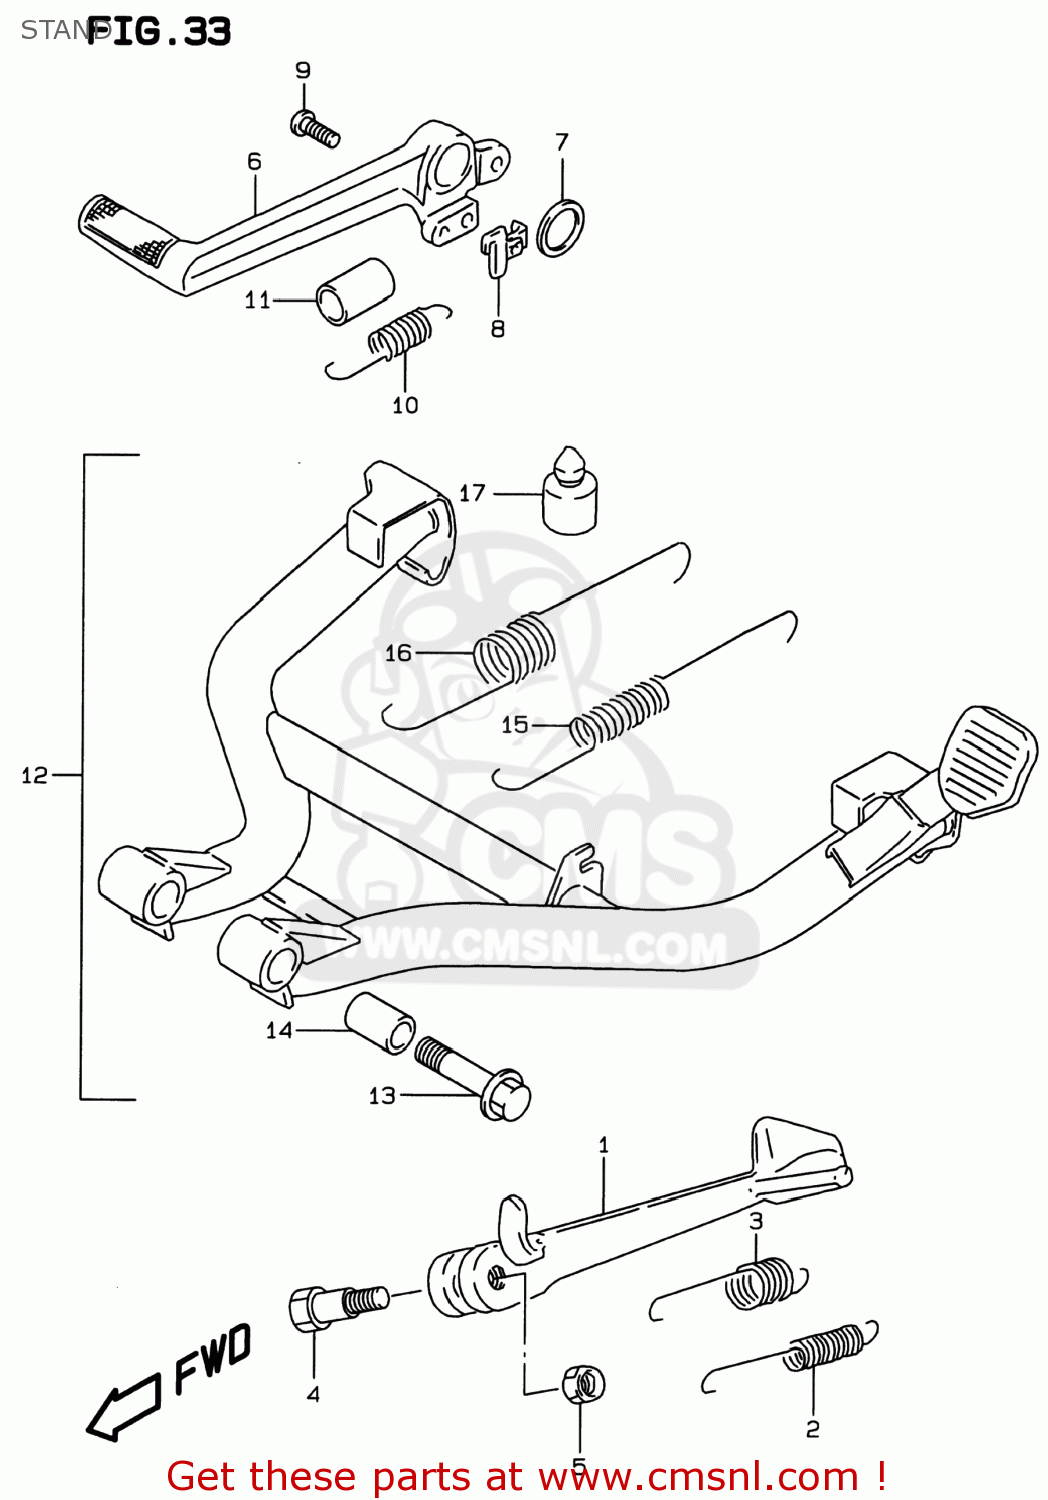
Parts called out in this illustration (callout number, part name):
1	STAND,PROP
2	SPRING
3	SPRING
4	BOLT(10X34)
5	NUT
6	PEDAL,BRAKE
7	WASHER(18X24X1)
8	BRACKET,STOP LAMP SWITCH SPR
9	SCREW
10	SPRING
11	TUBE,BRAKE SPRING GUIDE
12	STAND,CENTER
13	BOLT(10X48)
14	SPACER(10X16X25.5)
15	SPRING
16	SPRING OUTER
17	CUSHION
